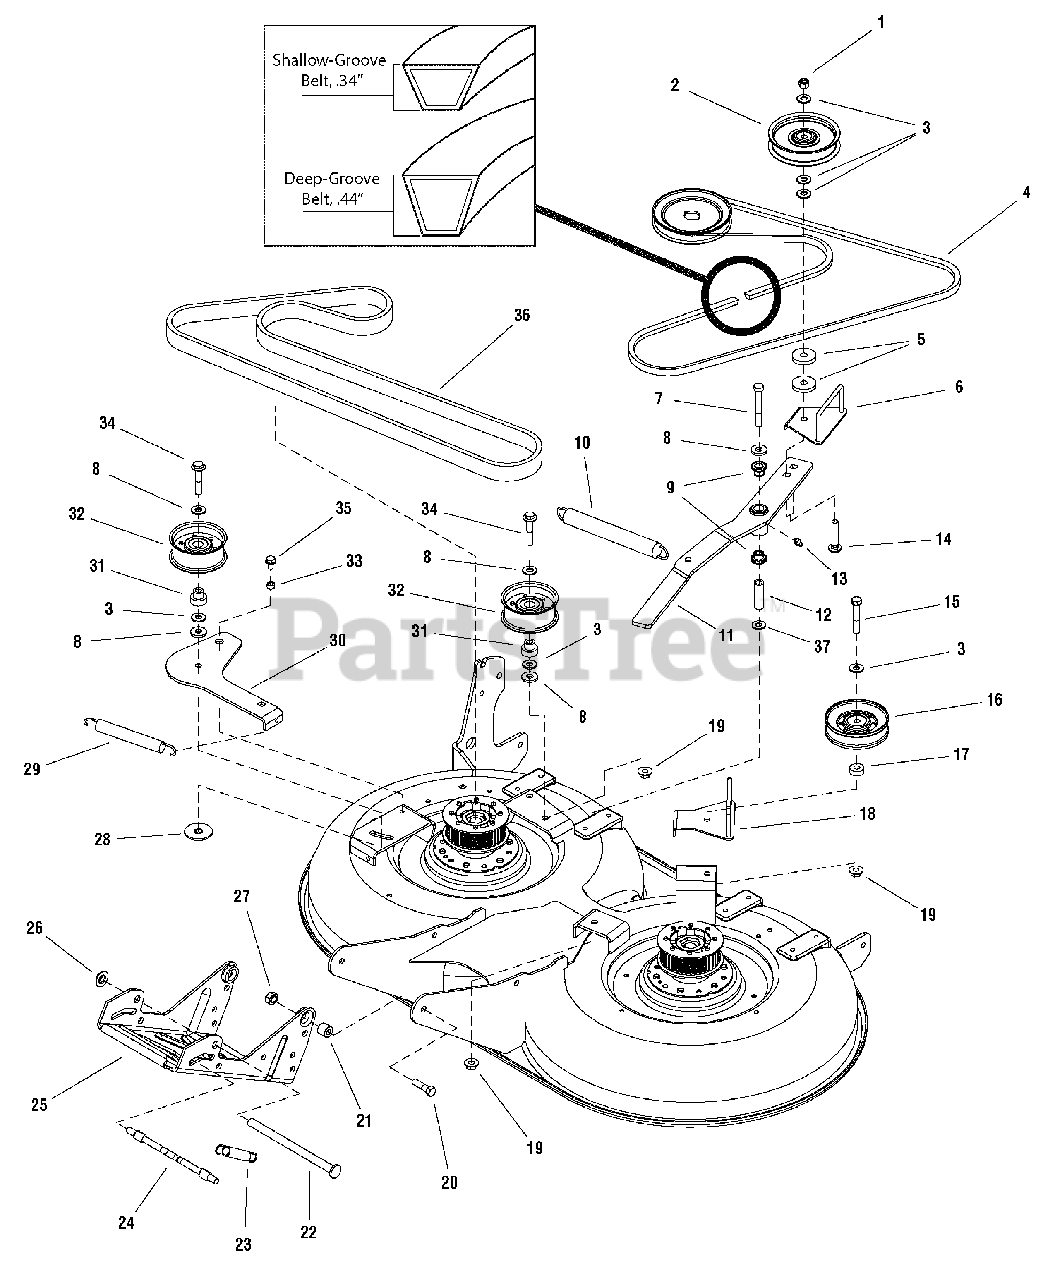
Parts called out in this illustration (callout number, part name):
1	NUT, Hex Lock, ESNA, 3/8-16
2	PULLEY, Idler
3	WASHER, 3/8
4	V-BELT, PTO, Front, .34" Shallow-Groove
4	V-BELT, PTO, Front, .44" Deep-Groove
5	WASHER
6	BELT GUIDE
7	CAPSCREW, Hex Head, 3/8-16 x 3 G8
8	WASHER, 3/8
9	BUSHING
10	SPRING, Extension, Idler Arm
11	ARM ASSEMBLY, with Bushing & Fitting, 38 Tooth
12	SPACER, Hardened
13	FITTING, Grease, 1/4-28 Thread
14	CARRIAGE BOLT, 3/8-16 x 2-1/4
15	CAPSCREW, Hex Head, 3/8-16 x 2-1/4
16	PULLEY
17	SPACER
18	BELT GUIDE
19	NUT, Hex, Flange, Whizlock, 5/16-18 x 1/2
20	CAPSCREW, Hex Head, 3/8-16 x 1-3/8
21	SPACER
22	ROD
23	SPRING, Extension
24	ROD
25	HITCH, Mower
26	NUT, Push, 1/2
27	NUT, Hex Toplock Spiral Flange, 3/8-16
28	WASHER & NUT ASSEMBLY, 3/8 x 1-1/2
29	SPRING, Extension
30	ARM, Idler
31	HUB
32	PULLEY, Idler
33	SPACER
34	SCREW, Hex Head, Flange 3/8-16 x 2
35	SCREW, Taptite, 5/16-18 x 5/8
36	BELT, Timing, 38" Tooth
37	WASHER, 3/8
